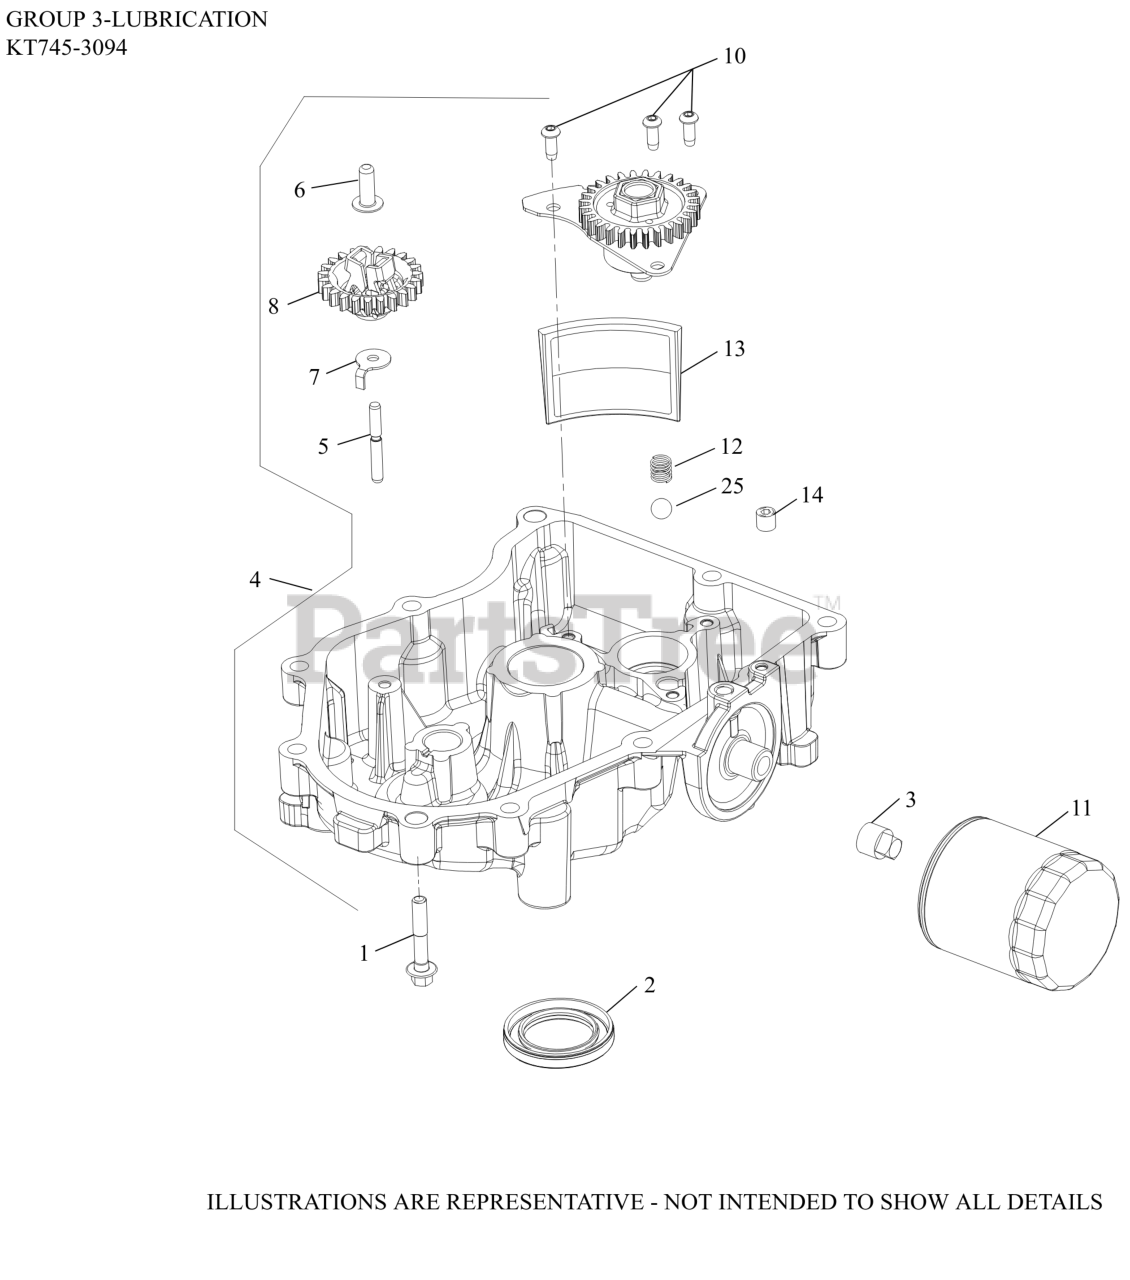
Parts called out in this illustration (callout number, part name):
1	SCREW, FLG M8X1.25X45
3	PLUG, SQ HD PIPE 3/8"
4	OIL PAN ASSEMBLY, (ROLLER BURNISHED)
5	SHAFT, GOVERNOR GEAR
6	PIN, GOVERNOR REGULATING
7	TAB, LOCKING
8	KIT, GOVERNOR GEAR
10	SCREW, BUTTON HEAD
11	OIL FILTER
12	SPRING, COMPRESSION
13	SCREEN, OIL
14	PLUG, CTSK PIPE 1/8"
25	PRESSURE RELIEF BALL
